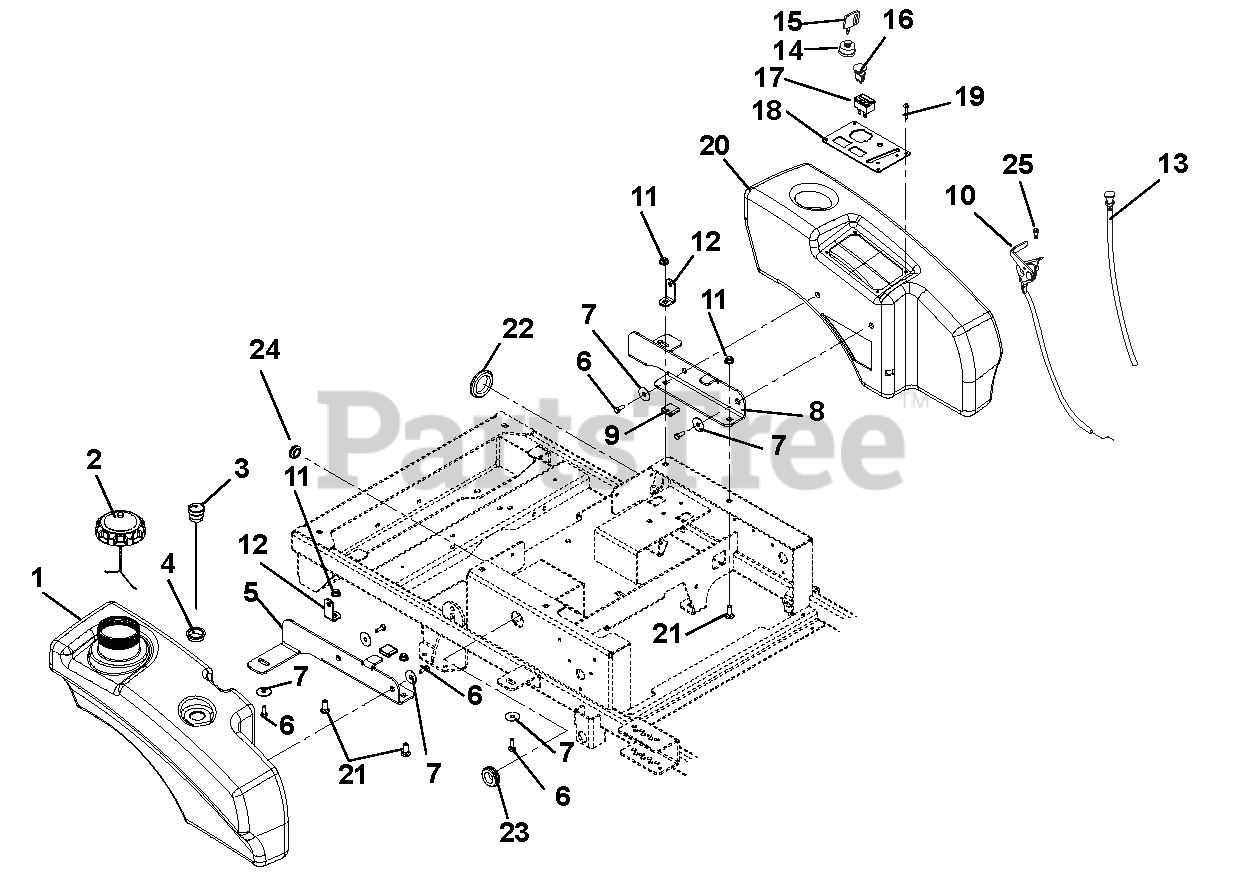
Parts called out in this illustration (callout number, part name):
1	KIT, XL TANK REPLACEMENT
2	CAP, FUEL
3	GAUGE, REMOTE FUEL 10.0"
4	GROMMET, FUEL GAGE
5	BRKT, RH REAR TANK MOUNT
6	BLT-SERHFWH .312-18X.50 YWZC
7	WSHR-FL-STL .347X1.254X.048YWZ
8	BRKT, LH REAR TANK MOUNT
9	GRIP, RUBBER (1.0X1.0X.187)BLK
10	CABLE-THROTTLE
11	@NUT-LK-NYL-FLG .38-16 YWZC
12	BRKT, HOOD PIVOT
13	CABLE, CHOKE
14	KEY SWITCH
15	KEY -W/CAP
16	SWITCH, CLUTCH
17	HOUR METER - DIGITAL
18	CONTROL PANEL
19	RIVET, PLASTIC .195 DIA.
20	FENDER, XL
21	@BLT-RDHDSQNK .38-16X1.00 G5YZ
22	GROMMET 1.70ID X 2.0OD
23	GROMMET 1.0ID X 1.38 OD
24	GROMMET,RUBBER 5/8 ID/1.13 OD
25	@SCR-TAP 10-24X.50 HWH TR YWZC
